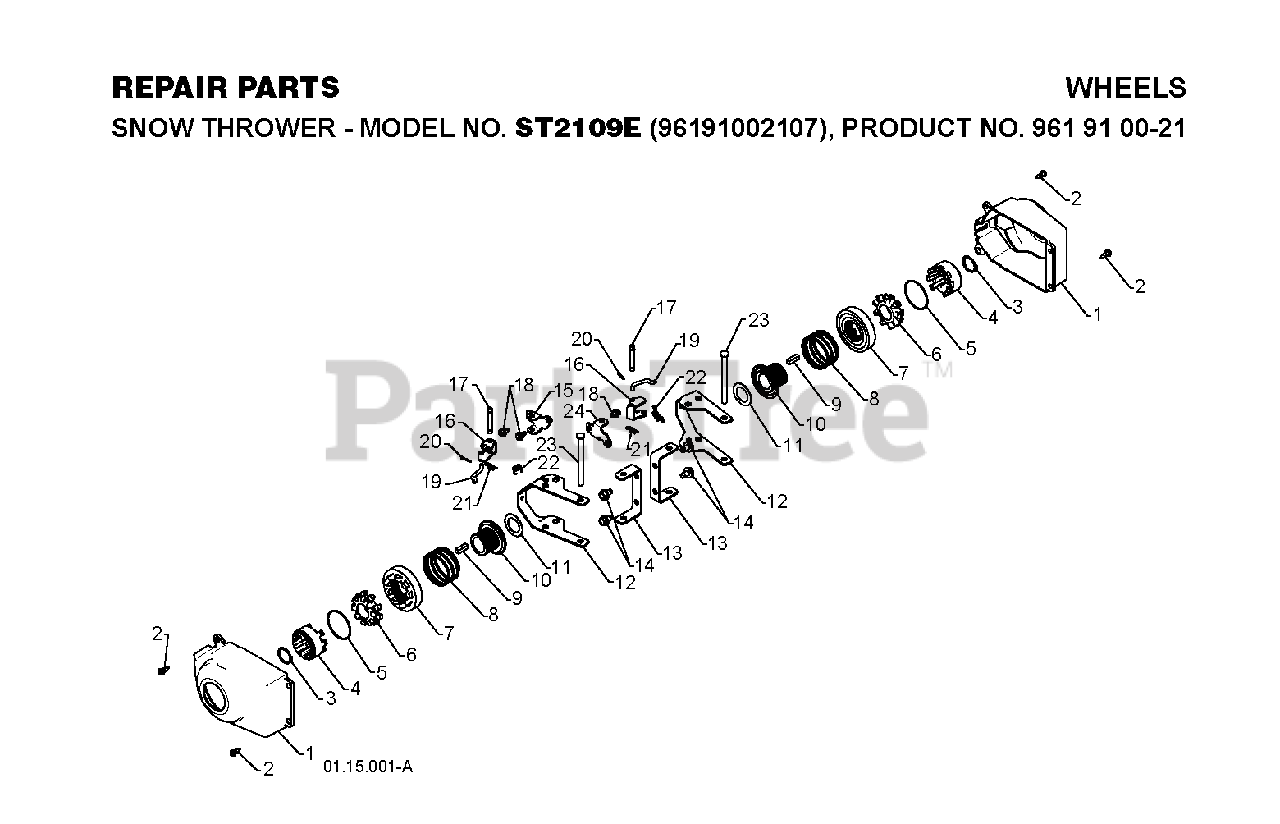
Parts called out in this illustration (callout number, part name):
1	COVER, POWER STEERING
2	SCREW, HEX HEAD, TAPPING
4	DRIVER WHEEL
5	RING, WIRE RETAINER
6	LOBE WHEEL
7	SLIDE.CLUTCH
8	SPRING, CLUTCH SLIDE
9	KEY, SQUARE 1/4 X .875
10	LOBE.AXLE
11	WASHER TRUST 1"
12	YOKE, STEERING
13	BRACKET.STEER.PNT.BLACK
15	BRKT.STEER.PIVOT.RH
16	BELLCRANK.STEER
17	PIN, STEERING BELLCRANK
19	LINK.STEER.YOKE
20	RETAINER CLIP
21	RETAINER CLIP PM
22	SPRING LATCH
23	PIN, STEERING LEVER
24	CONTROL SHAFT
